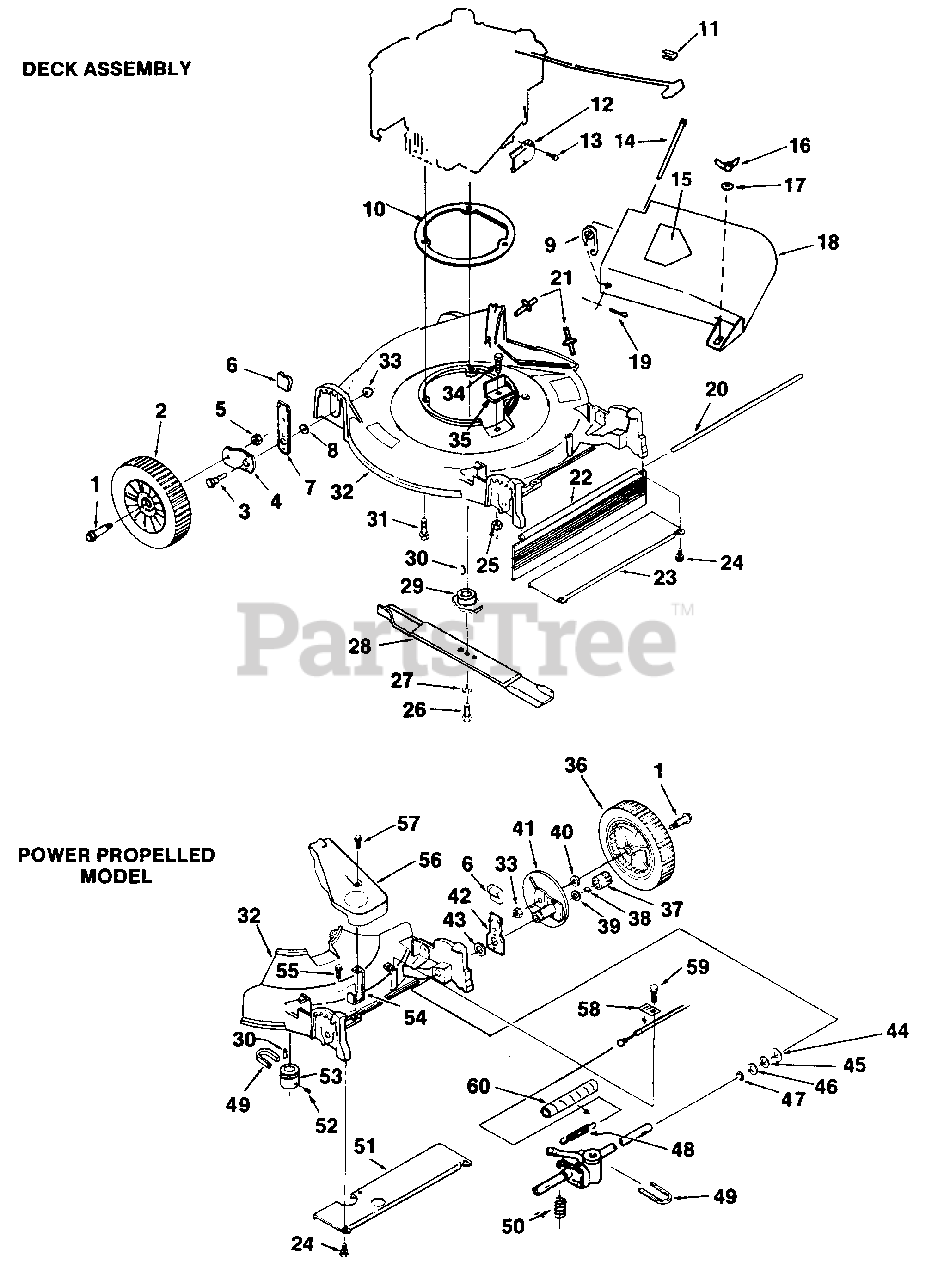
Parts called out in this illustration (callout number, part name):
1	BOLT- Axle (3/8-16)
2	WHEEL & TIRE
3	BOLT- Hex hd. (5/16-18) Height Adjusting
4	ARM- Wheel adjusting
5	NUT- Hex (3/8-24) Centerlock
6	KNOB- Index spring
7	INDEXING SPRING & PIN ASSY.
8	SPACER- Height adjusting
10	RING- Engine
11	ROPE STOP
12	DEFLECTOR- Muffler
13	SCREW- Hex hd. (8-32 x 3/8")
14	PIN- Hinge
15	LABEL- Warning
16	NUT- Wing WC-040
17	WASHER- Flat 1/4" plain
18	COVER- Discharge
19	PIN- Cotter (3/32 x 3/4")
20	ROD- ZP Drag flap
22	FLAP- Drag
23	COVER- Rea:
24	SCREW- Hex washer (1/4-20 x 3/4")
25	NUT- Hex lock (1/4-20)
26	SCREW- Hex hd. (3/8-24 x 1
27	WASHER- Lock 3/8" hvy.
28	BAR CUTTER
29	ADAPTOR- Blade
30	KEY- Woodruff (5/8 x 3/16")
31	SCREW- Hex hd. (3/8-16 x 1 1/2")
33	NUT- Flange (5/16-18)
34	SCREW- Hex hd. (1/4-20 x 1/2")
35	COVER- Belt opening
36	WHEEL & TIRE ASSY.
37	PINION- R.H.
41	DRIVE WHEEL SUPPORT ASSY.
42	INDEXING SPRING & PIN ASSY.
43	SPACER- Rear height adj.
46	WASHER- (Shim)
47	RING- Eaton
48	SPRING- Extension
49	BELT- Drive
50	SPRING- Compression
51	COVER- Rear
52	SCREW- Set (1/4-20 x 3/8")
53	PULLEY- Drive
54	BRACKET- Gear box cover
55	SCREW- Sems thd. (1/4-20 x 9/16")
56	COVER- Drive
57	SCREW- Hex hd. (1/4-20 x 3/4")
58	CLAMP- Cable
59	SCREW-Hex hd. (1/4-20 x 5/8")
60	COVER- Spring
